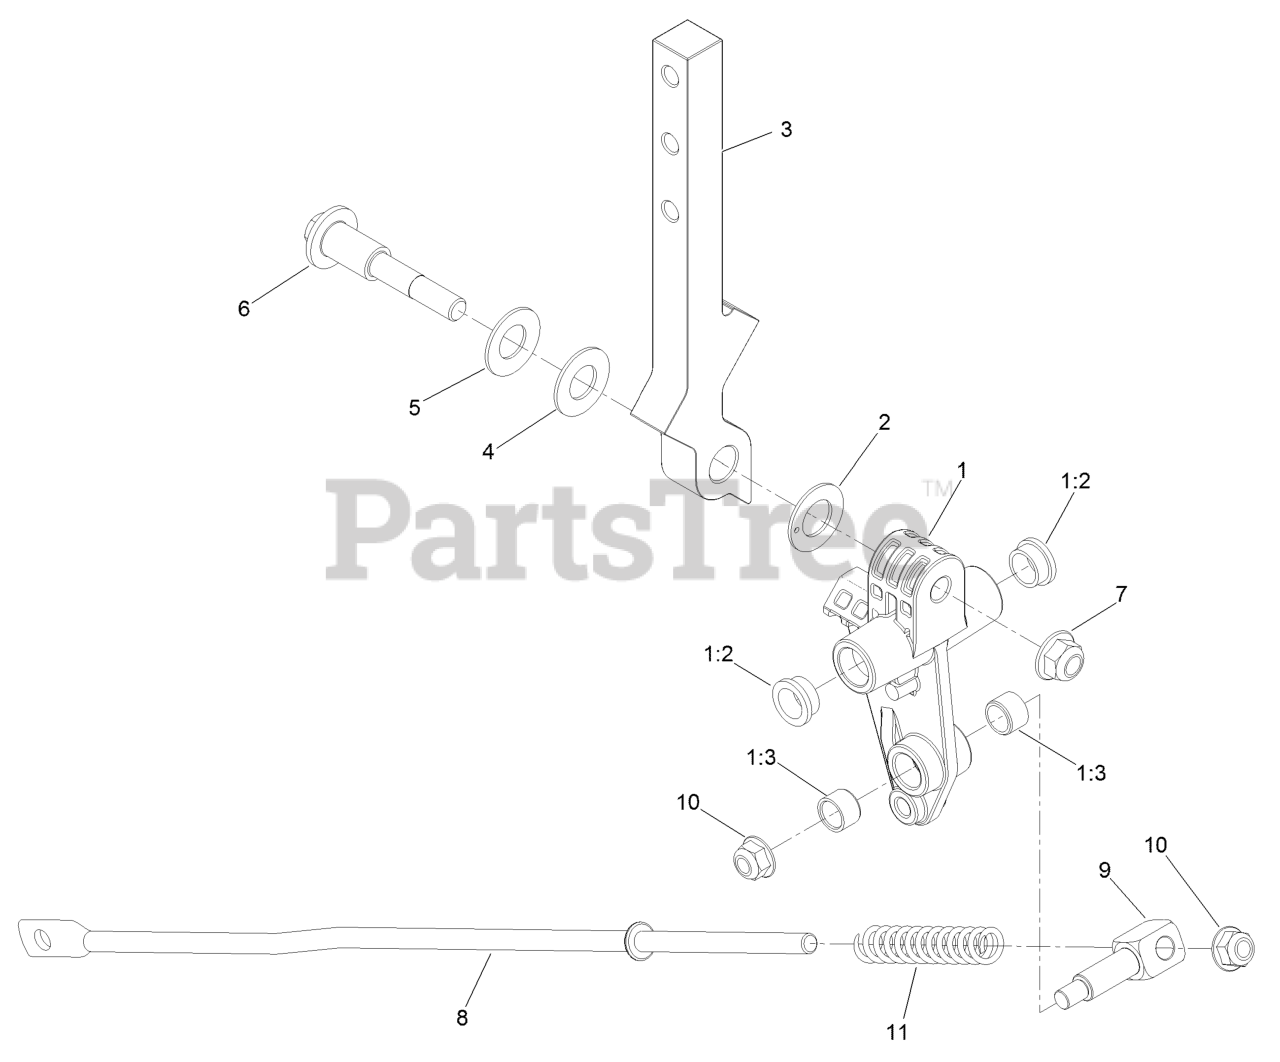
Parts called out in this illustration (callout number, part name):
1	CONTROL ARM ASM
1:2	BUSHING
1:3	BUSHING-SLEEVE
2	WASHER-FRICTION
3	ARM-CONTROL
5	WASHER-BELLEVILLE
6	BOLT-PIVOT
7	NUT-HF, NI
8	LINK-CONTROL
10	NUT-HF, NI
11	SPRING-RETURN, NEUTRAL
